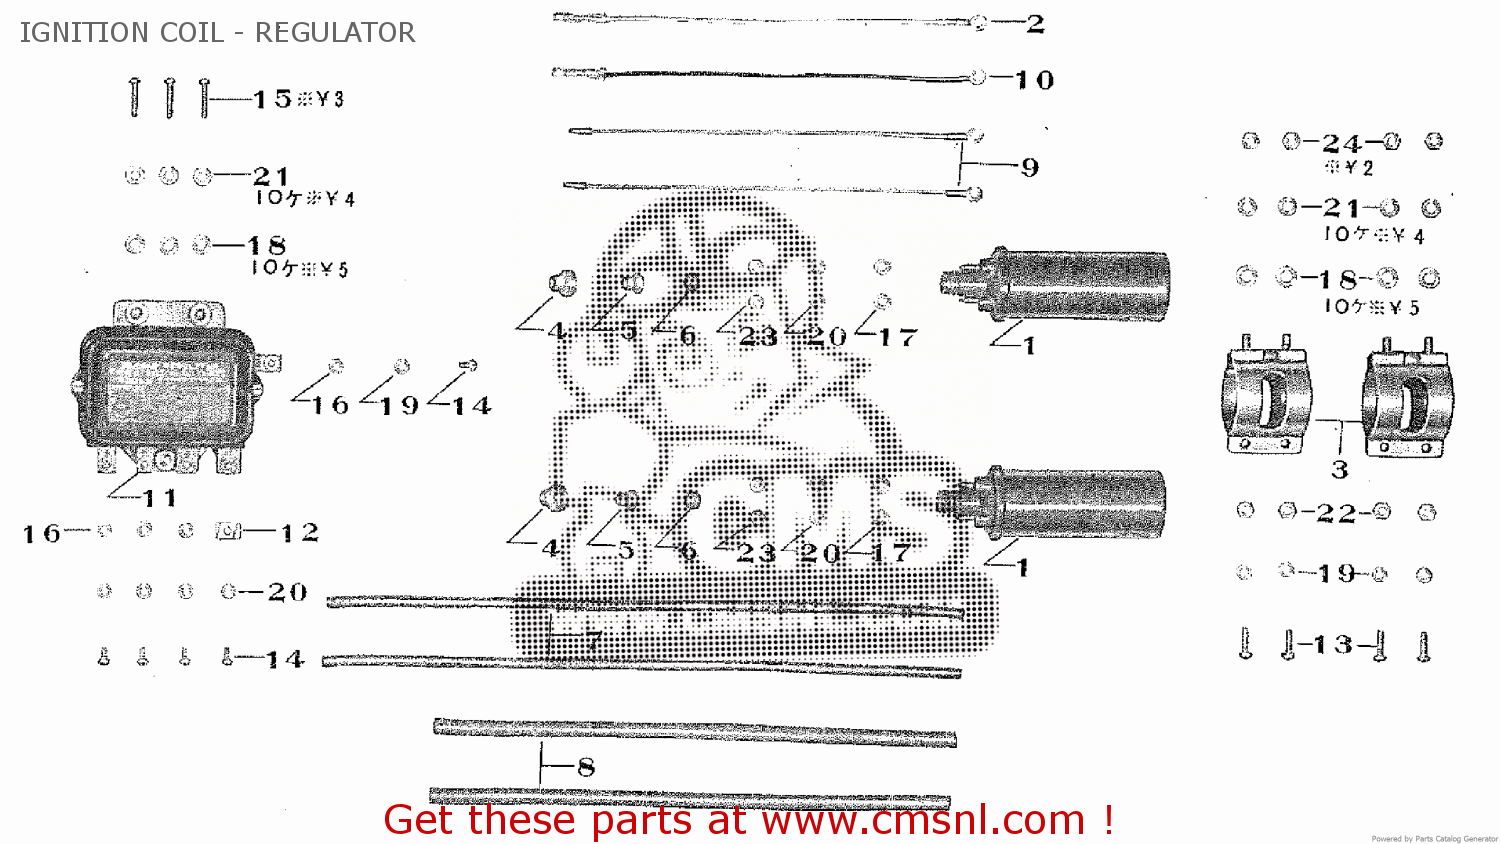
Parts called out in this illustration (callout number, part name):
1	IGNITION COIL COMP.
2	LEAD CORD (WHITE)
3	IGNITION COIL BAND COMP.
4	HIGH TENSION CORD SET CAP
5	HIGH TENSION CORD SET RING
6	HIGH TENSION CORD BUSH
7	HIGH TENSION CORD
8	HIGH TENSION CORD TUBE
9	LEAD CORD (PINK)
10	LEAD CORD (BLACK)
11	REGULATOR ASSY.
12	TERMINAL SET WASHER
13	4X14 SCREW
14	5X8 SCREW
15	6X18 CROSS SCREW
16	5MM PLANE WASHER
17	5MM LIGHT PLANE WASHER
18	6MM PLANE WASHER
19	4MM PLANE WASHER
20	5MM SPRING WASHER
